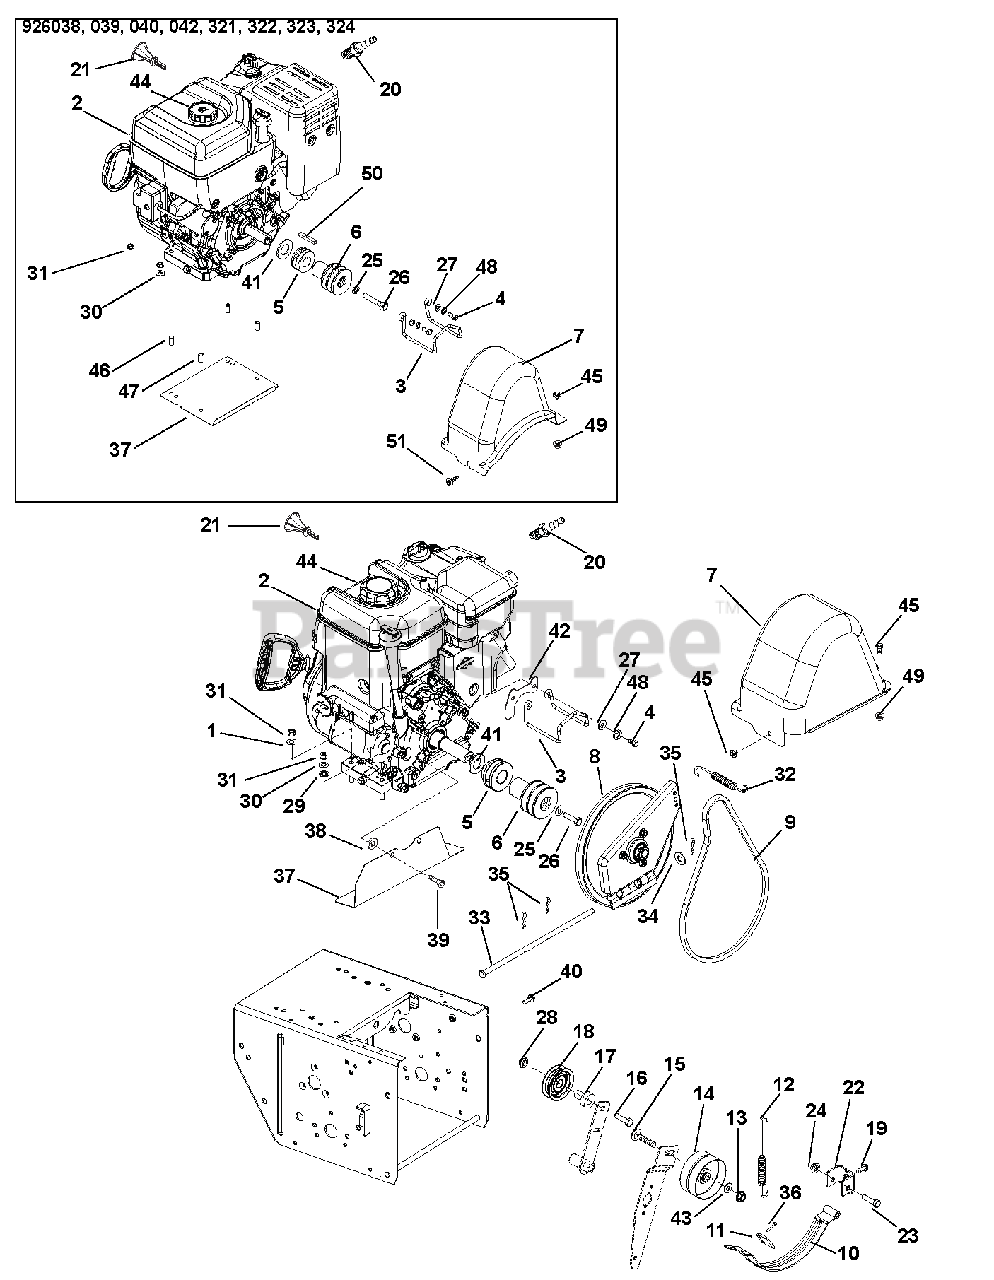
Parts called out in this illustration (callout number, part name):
1	WSHR-LK .312X.097 HVY YWZC
2	ENGINE, BRIGGS PF 1650, 12V
2	ENGINE, BRIGGS PF 2100, 120V
2	ENGINE, BRIGGS PF 2100, 240V
3	FINGER, BELT
4	BLT-HEX .31-24X.75 YWZC GR5
5	SHEAVE, DRIVE
5	SHEAVE, DRIVE 420 BRIGGS
6	SHEAVE, ATTACHMENT 2-GRV
7	COVER, BELT
7	COVER, BELT-LARGE PRO
8	PLATE, SWING ASSEMBLY-DEEP
9	V-BELT, 3L-WRAPPED
10	ARM, BRAKE-ATTACHMENT
11	PAD, BRAKE
12	SG-TENS .056X.60X4.40
13	@NUT-LK-CTR-JAM .375-16 YWZC
14	IDLER, FLAT-2.75 OD X .375 ID
15	@BLT-RHDSSQNK .38-16X1.75 G5YZ
16	@BLT-HEX .31-18X1.25 GR5 YWZC
17	SPCR, BRG .315X.50X.688X.281
18	IDLER
19	SCR-TAP .25-20X.50 HWH TR YWZ
20	PLUG, SPARK
20	PLUG, SPARK 20HP B&S VANGUARD
21	KEY, PUSH/PULL BRIGGS
21	KEY, IGNITION ROTARY B&S
22	PIVOT, BRAKE
23	@BLT-HEX .31-18X2.00 GR5 YWZC
24	@NUT-LK-TOP-FLG .31-18 YWZC
25	@WSHR-LK .38X.094 REG YWZC
25	@WSHR-LK .44X.109 REG YWZC
26	BLT-HEX .38-24X2.25 YWZC GR5
26	BLT-HEX .44-20X2.50 GR5 YWZC
27	@WSHR-FL-STL.344X.688X.065YWZC
28	@NUT-LK-TOP-FLG .31-18 YWZC
29	WSHR-LOCK INT .31 YWZC
30	@WSHR-FL-STL.344X.688X.065YWZC
30	@WSHR-FL-STL.38X.875X.083 YWZC
31	@NUT-LK-CTR .31-18 YWZC
31	@NUT-HEX .31-18 YWZC
31	@NUT-LK-CTR-FLG .31-18 YZ GR F
32	SG-TENS .048X.50X2.8
33	PIN, PIVOT
34	@WSHR-FL-STL.406X.812X.065 YWZ
35	PIN-HAIR, ENDRIES #25 YWZC
36	RVT-POP .187 YZ
37	BAFFLE, ENGINE
37	BAFFLE,ENGINE-PRO SERIES
38	WSHR-FL-STL .536X1.07X.109 YZ
39	SCR-MCH.31-24X.75FLCTRSK EP80
40	@SCR-TAP .25-20X1.50 HWH TR YZ
41	WSHR-FL-STL- 1.062X2.0X.134 YZ
42	GUARD, BELT COVER - BRIGGS
43	@WSHR-FL-STL.38X.875X.083 YWZC
44	CAP, FUEL - BRIGGS & STRATTON
45	SCR-TAP .25-20X.50 LGHWH TR YZ
46	BSHG-SLV .325X.400X.795
47	BSHG-SLV .328X.50X.75
48	WSHR-LK .312X.097 HVY YWZC
49	NUT-PUSH .25X.50 O.D.
50	KEY-SQ .25X.625X.25 SAE 8630
51	SCR-TAP .25-20X.5 CAPTIVE
